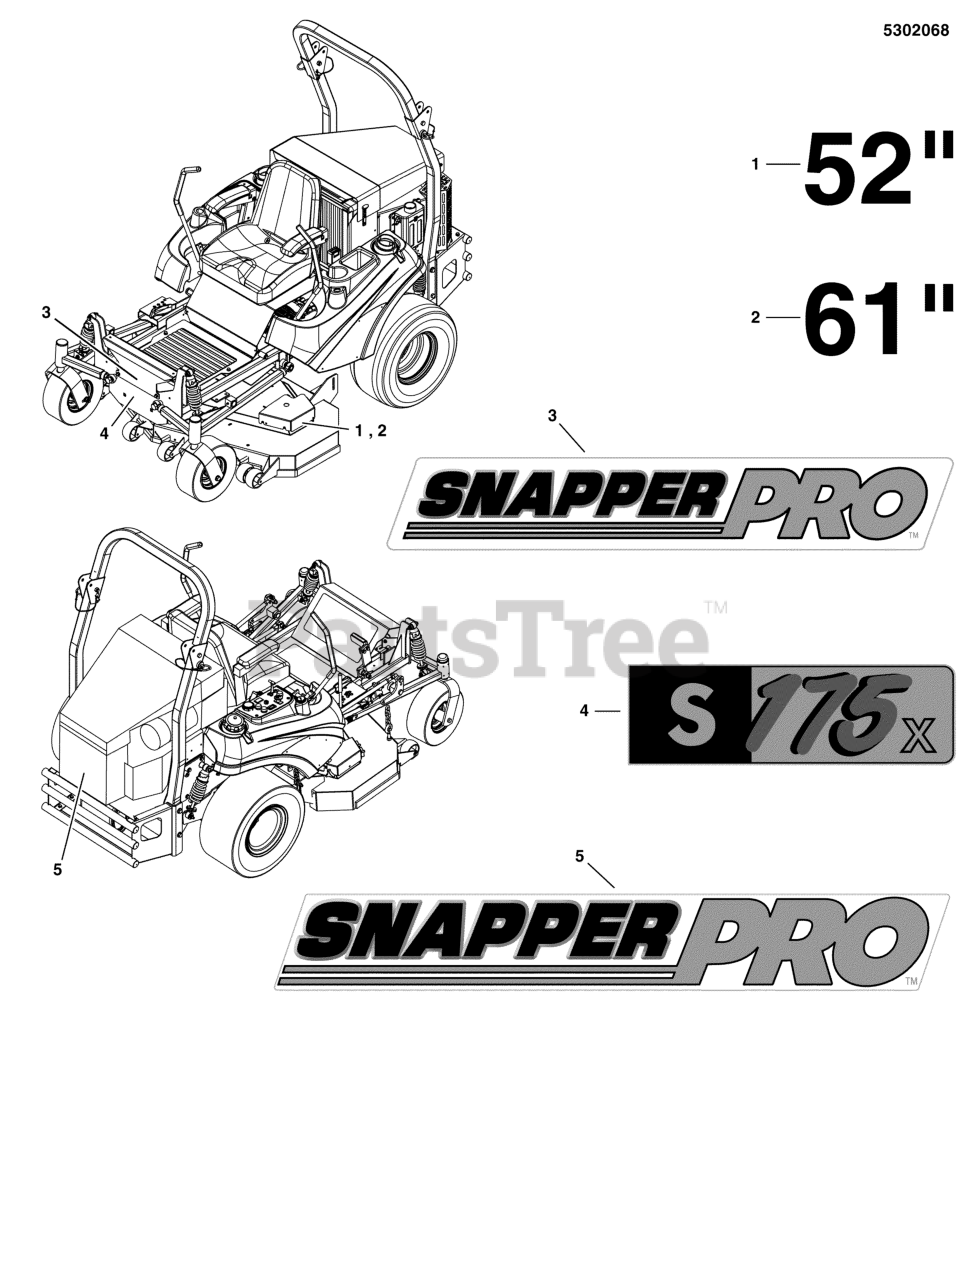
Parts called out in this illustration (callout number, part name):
1	DECAL, 52
2	DECAL, 61
3	DECAL, SNAPPER PRO, HEAT
4	DECAL, LOGO, S175X
5	DECAL, SNAPPER PRO, 12.87 X 1.83
